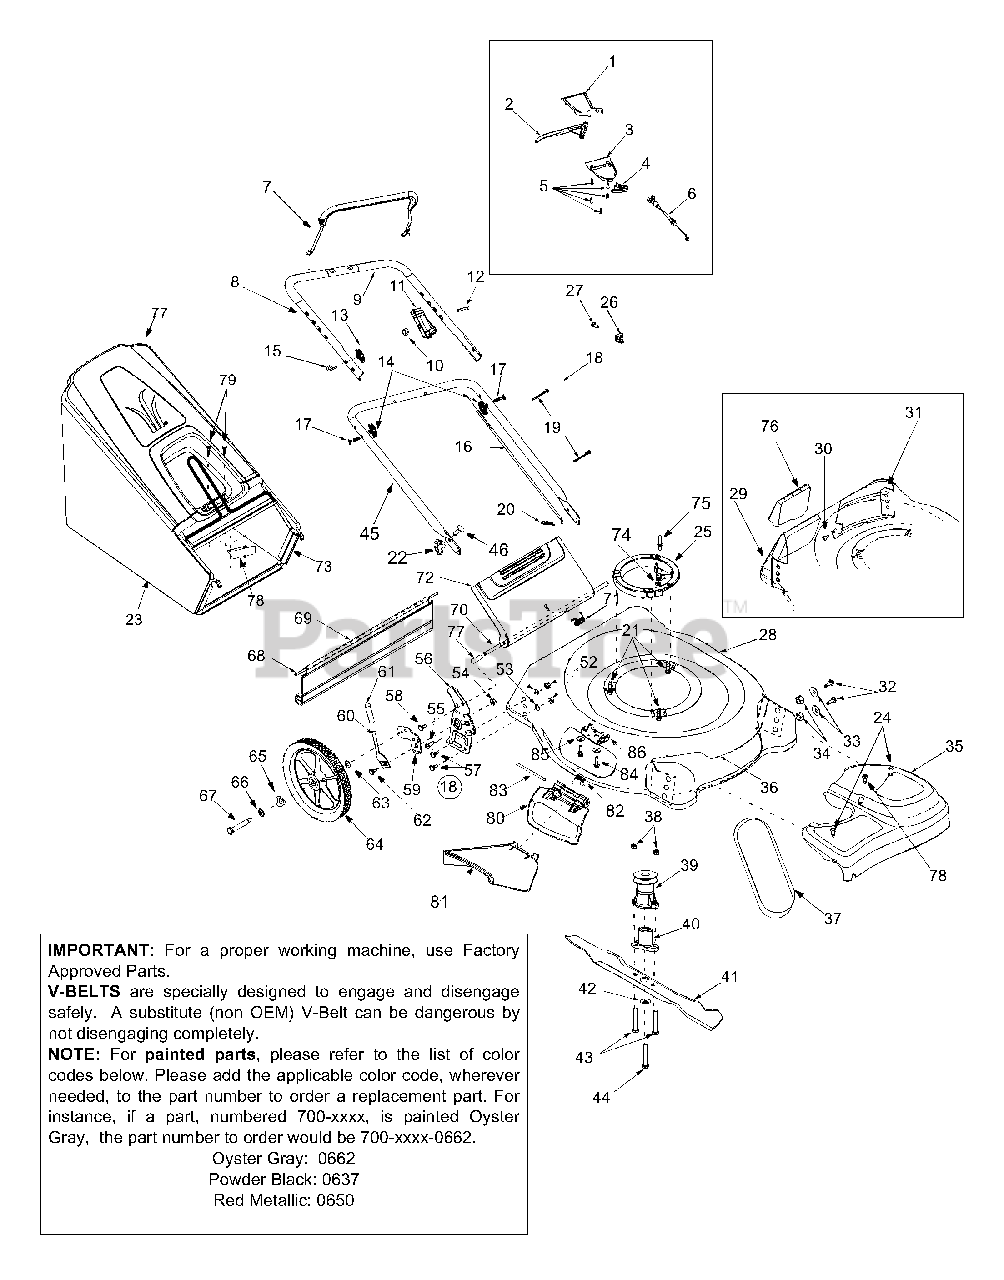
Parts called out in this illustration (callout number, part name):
1	Upper Drive Cover
2	Drive Lever
3	Lower Drive Cover
4	Mounting Cap
5	Screw # 10-16 x .75
6	Drive Cable
7	Deluxe Control Lever
9	Foam Grip, 9"
10	Hex Lock Nut, 1/4-20
11	Throttle Housing
12	Oval C-Sunk Screw 1/4-20 x 1.31
16	Control Cable, 39"
17	Carriage Bolt 5/16-18 x 2.0
18	RH Bracket Ass'y
19	Cable Tie
21	Self-Tapping Screw
22	Wing Knob
23	Grass Bag
24	Screw # 12 x .457
25	Engine Spacer
26	Clamp Casing
27	Hex Screw TT #10-32 x .625
30	Screw AB: 1/4-14: .625
32	Hex Screw 3/8-16 x .75
33	Bell Washer .39 x 1.13 x .062
34	Hex Nut 3/8-16
35	Transmission Cover (Gray)
38	Hex Nut 1/4-20
39	Drive Pulley
40	Blade Adapter
41	21" Mulching Blade
42	Flat Washer .516 x 1.5 x .134
43	Hex Screw 1/4-20 x 1.50
44	Hex Screw 3/8-24 x 2.50
46	Carriage Bolt, 1/4-20 x .75"
52	Hex Lock Nut
53	Bell Washer .39 I.D. x 1.38 O.D.
54	Hex Flange Lock Nut 3/8-16
55	Hex Scr. w/Washer 1/4-14 x .625
57	Hex Bolt 3/8-16 x 1.0"
58	Pan Head Screw
59	RH Pivot Bar
60	Height Adj. Lever
62	Shoulder Scr .500 Dia. x .434
63	Washer .401 x .870 x .063
64	Wheel, 14 x 2 Gray (Link Trd.)
65	Spring Washer .50 I.D. x 1.0 O.D.
66	Flat Washer .510 x 1.373 x .04
67	Shoulder Screw
68	Wire
69	Rear Trailing Shield
71	Torsion Spring
77	Hardtop w/ logo
80	Mulching Plug (Hinged)
81	Chute Deflector
82	Torsion Spring
83	Hinge Pin
84	Tapp Scr. 1/4-20 x .500
85	Bell Washer .265 x .75 x .062
